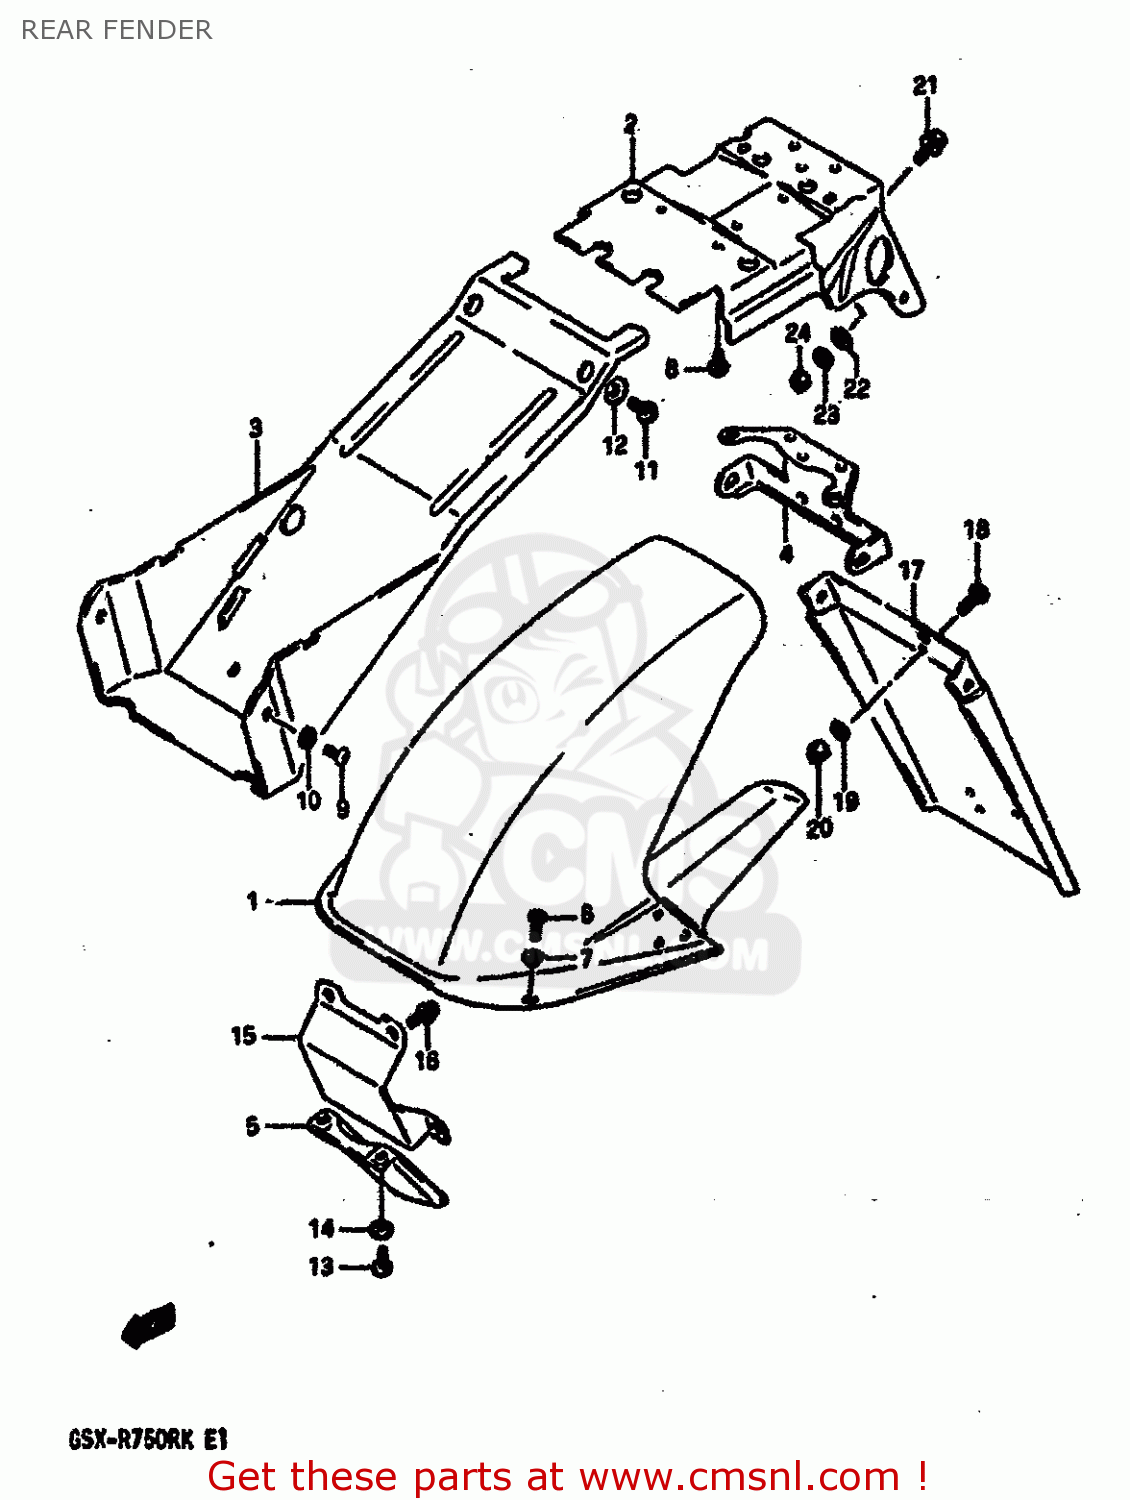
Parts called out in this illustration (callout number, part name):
1	BODY,REAR FENDER LOWER
2	BODY,REAR FENDER
3	BODY,REAR FENDER FRONT
4	BRACKET,REAR FENDER
5	GUARD,RR UNIT MUD
6	SCREW
7	WASHER
8	SCREW 6X12
9	SCREW, FRONT & REAR
10	WASHER
11	SCREW
12	WASHER (6.5X24X1.6)
13	SCREW
14	WASHER,LOCK
15	MUD GUARD,CUSHION LOWER
16	SCREW(6X16)
17	EXTENSION,REAR FENDER
18	SCREW
19	WASHER
20	NUT 6MM
21	BOLT,LICENCE PLATE
22	WASHER
23	WASHER
24	NUT 6MM
